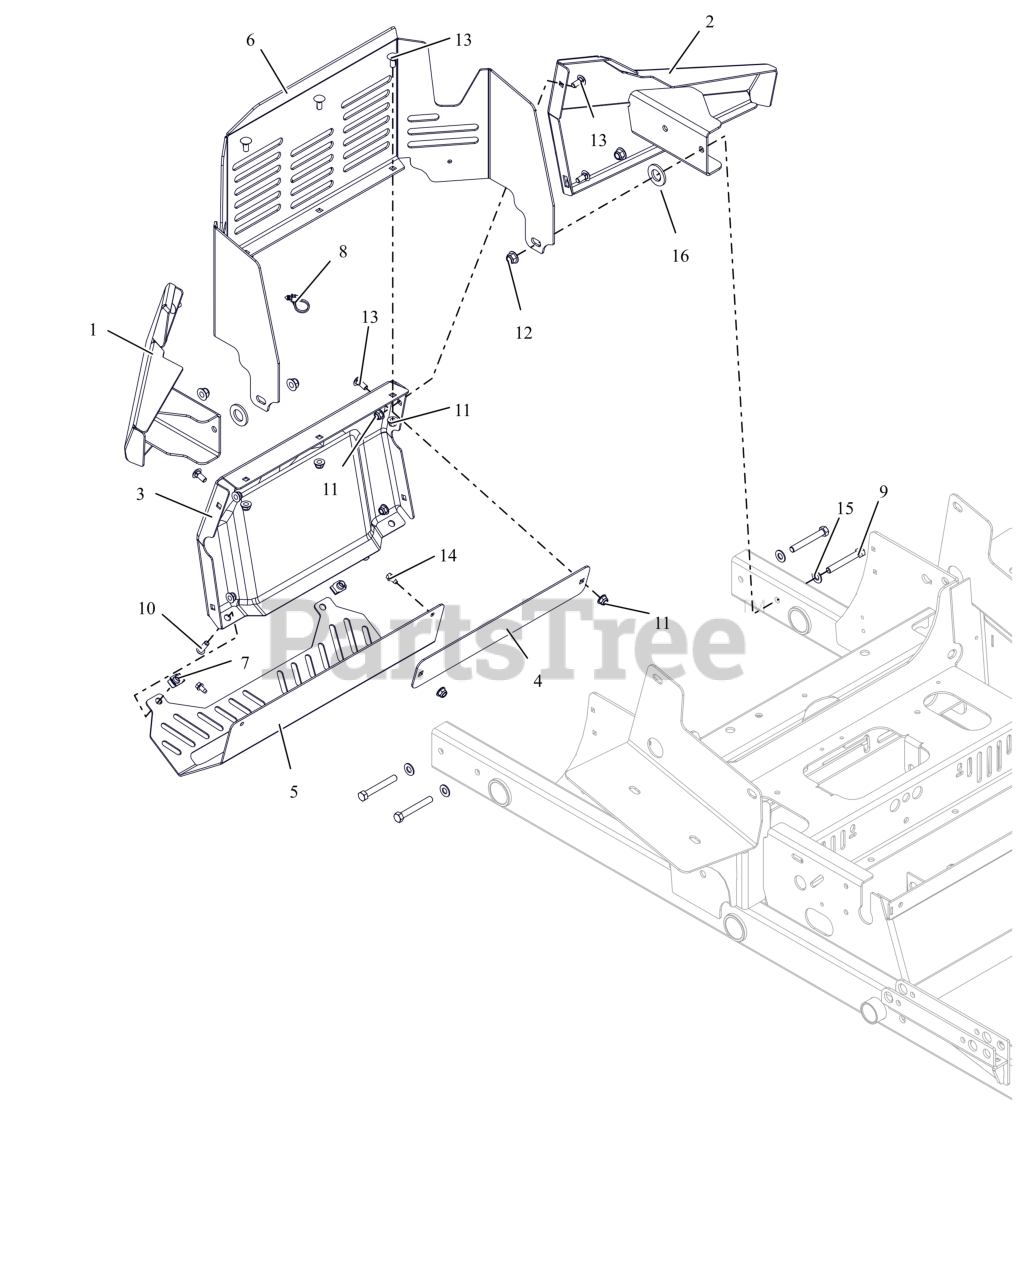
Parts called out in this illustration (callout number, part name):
1	WMT,RH REAR BMPR WING W/DECAL
2	WMT,LH REAR BMPR WING W/DECAL
3	PT200/400 REAR BUMPER - BLACK
4	BACKER PLATE - RED
5	PT200/400 MUFFLER GUARD - BLK
6	PT200 ENGINE GUARD - RED
7	NUT-CLIP RETAINER 5/16-18X.56
8	CABLE TIE W/ TREE (.25 HOLE)
9	BLT, HEX .38-16X2.75 G5 ZCC
10	BLT,SHCS-BTN .31-18X1.00 ZCC
11	NUT,NYL-FLG .31-18 GF ZCC
12	NUT,NYL-FLG .38-16 GF ZCC
13	BLT,RHSN .31-18X.75 G5 ZCC
14	SCR-TAP .25-20X.50 HWH ZCC
15	WSHR,FLT .406X.812X.065 ZCC
16	WSHR-FL-STL 0.812X1.469X0.134 ZCC
